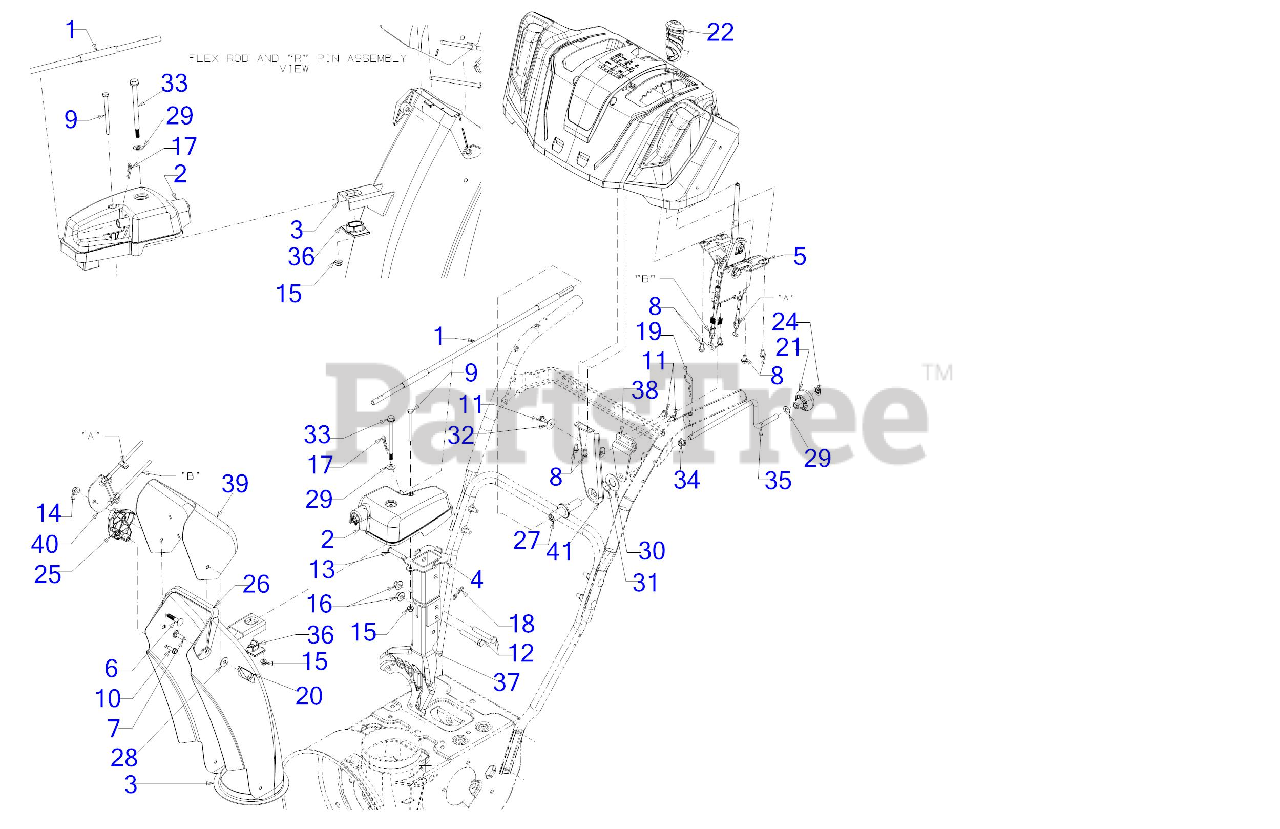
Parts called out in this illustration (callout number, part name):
1	CHUTE CONTROL SHAFT
2	WORM GEARBOX ASSEMBLY
5	2-WAY STEEL CHUTE CONTROL ASSEMBLY
6	CARRIAGE BOLT 5/16-18 x 1.50
7	CARRIAGE BOLT 5/16-18 x 1.00
8	HEX SCREW 1/4-15 x .50
9	SCREW 1/4-20 x 3.0 GR5
10	SCREW 1/4-15 x .750
11	SCREW 1/4-20X.625
12	SCREW 3/8-16 x 2.25 GR5
13	CLEVIS PIN 3/8 x 1.87
14	FLANGE LOCK NUT 5/16-18
15	FLANGE LOCK NUT
17	INTERNAL COTTER PIN
18	BOW TIE COTTER PIN 1/4-5/16
19	INTERNAL COTTER PIN
20	WING NUT KNOB
21	SHIFT KNOB
22	PTO HANDLE GRIP .355 ID
24	PUSH NUT
25	CHUTE TILT GUIDE
26	UPPER CHUTE ADAPTER
27	CHUTE ROD COUPLER
28	FLAT WASHER
29	FLAT WASHER
30	FLAT WASHER
31	WAVE WASHER .785X1.00X.012
32	FLAT WASHER
33	SHOULDER SCREW
34	BUSHING .380 ID
36	HELICAL GEAR CHUTE ADAPTER
38	ROD SUPPORT BRACKET
